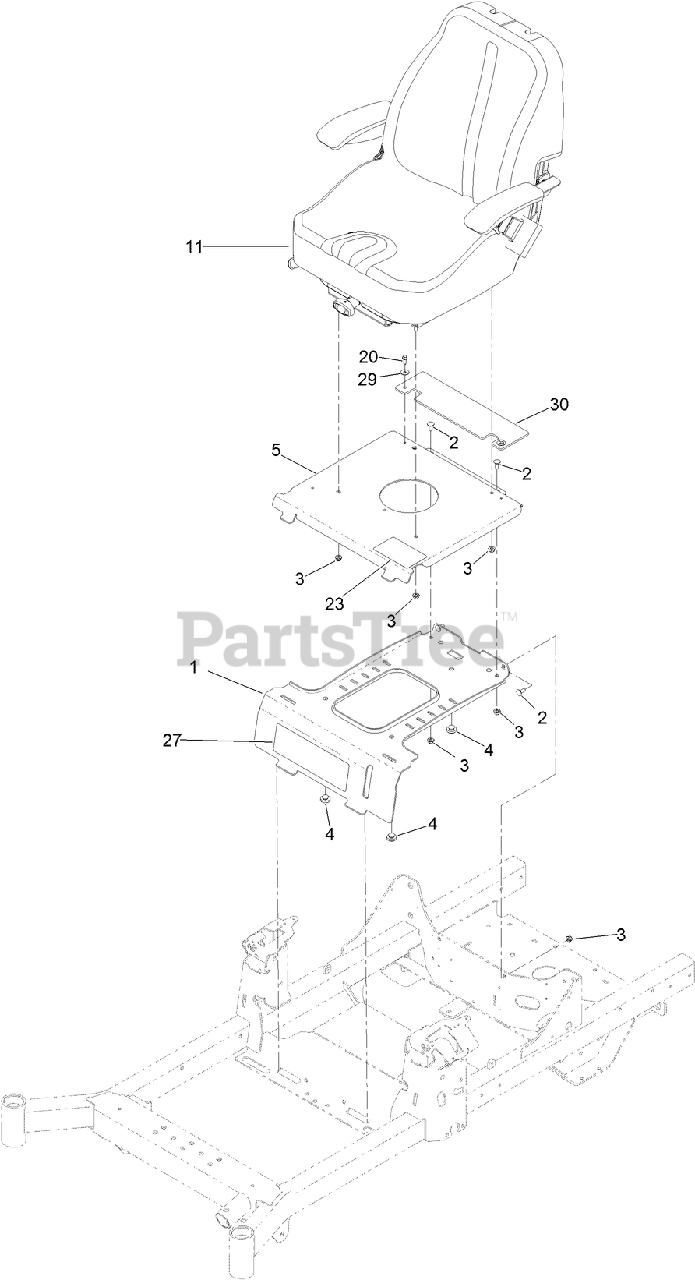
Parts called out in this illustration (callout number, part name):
1	PLATE-RETAINER, TANK
2	SCREW-CARR
3	NUT-HF, NI
4	BUMPER-SEAT
5	PLATE-SEAT, FIXED
11	SEAT ASM
20	SCREW-HWH, THREAD ROLL
23	DECAL-AID, SERVICE
29	WASHER
30	GUARD-RUBBER
